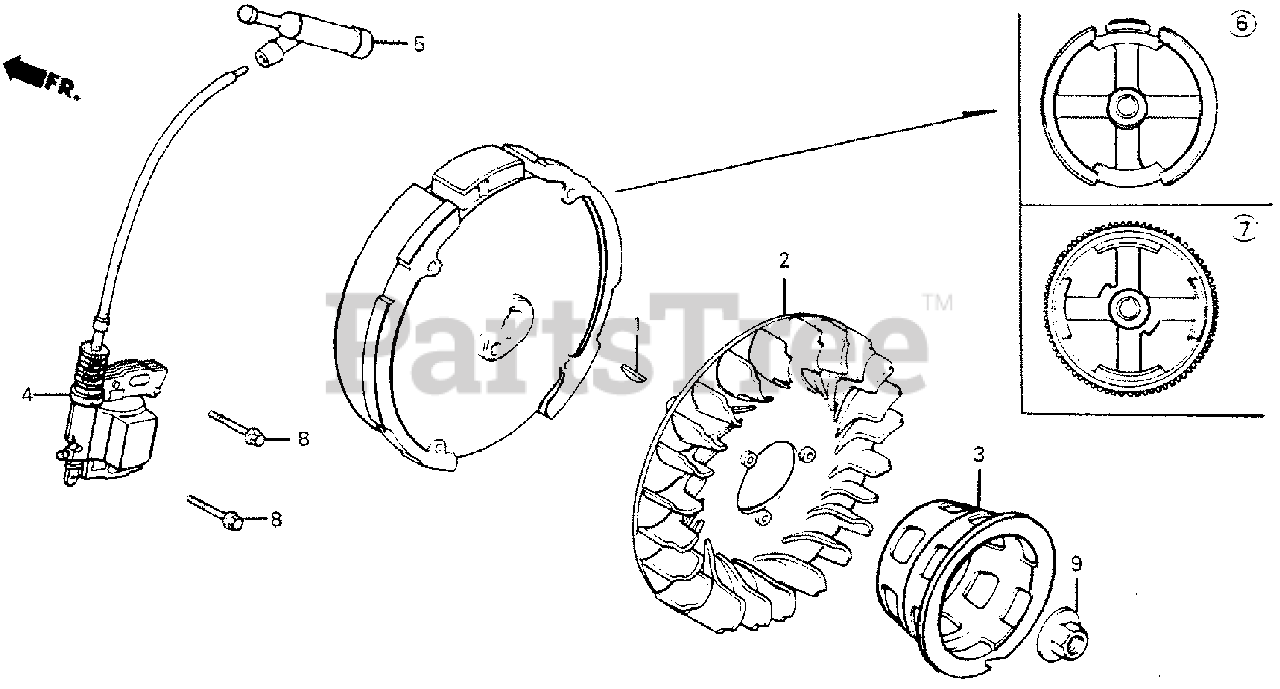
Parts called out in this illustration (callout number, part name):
1	KEY, SPECIAL WOODRUFF (25X18)
2	FAN, COOLING
3	PULLEY, STARTER
4	COIL ASSY., IGNITION
5	CAP ASSY., NOISE SUPPRESSOR
7	FLYWHEEL (STARTER MOTOR)
8	BOLT, FLANGE (6X25)
9	NUT, SPECIAL (14MM)
